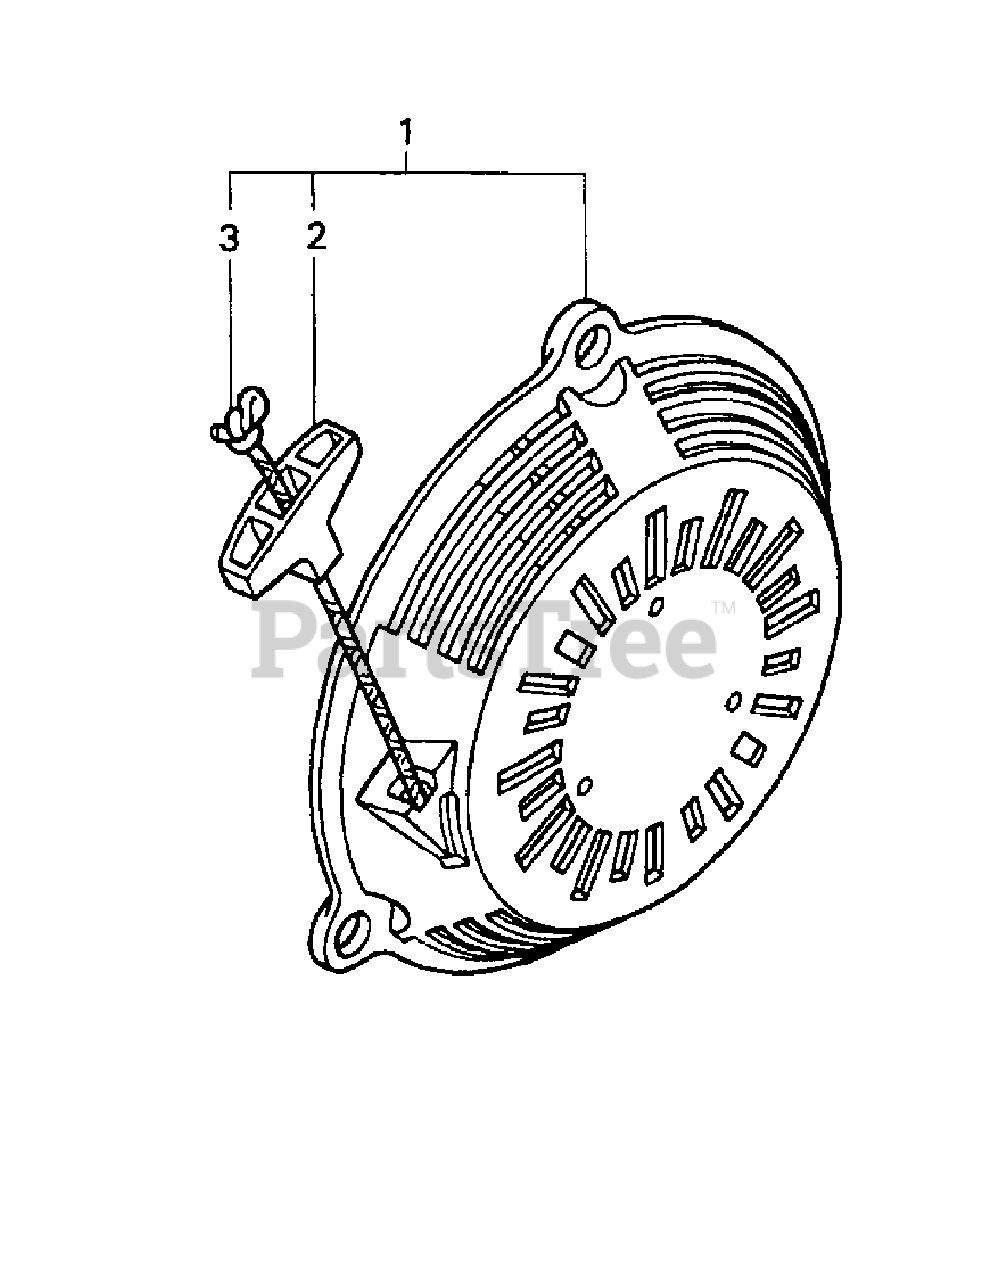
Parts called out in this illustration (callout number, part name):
1	Recoil Starter Assembly (Black)
2	Recoil Starter Knob
3	Recoil Starter Rope, #3.5 x 52
